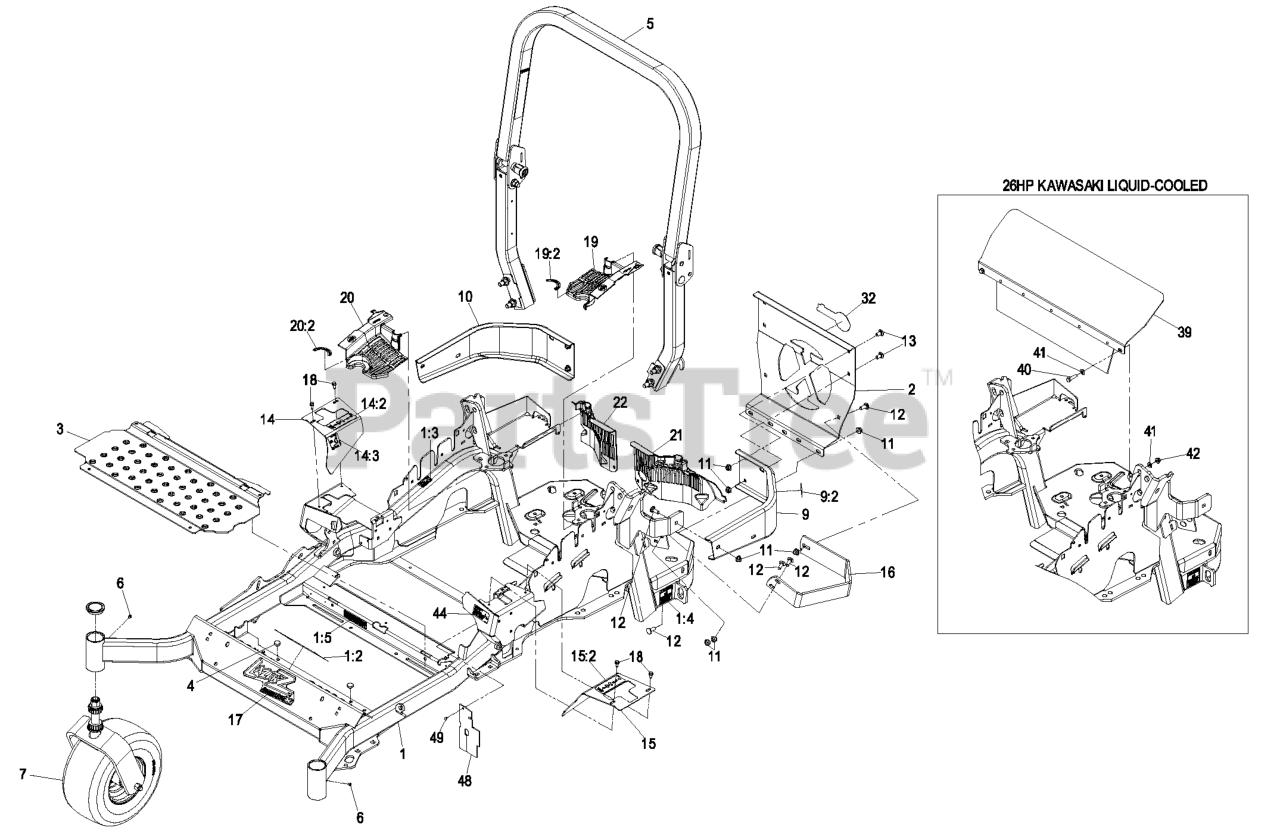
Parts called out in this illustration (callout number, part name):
1	MAIN FRAME ASM
1:2	DECAL-WARNING
1:3	DECAL-CAUTION
1:4	DECAL-BELT DRIVE
1:5	DECAL-ARRESTER, SPARK
2	PLATE,REAR GUARD
5	ASM,ROPS SERVICE EXMARK
9	LH BUMPER ASM
9:2	DECAL-CAUTION
10	BUMPER-RH
11	NUT-HF, NI
12	SCREW-CARR
13	SCREW-CARR
14:2	DECAL-MOTION CONTROL
15	LH MOTION CONTROL COVER ASM
15:2	DECAL-MOTION CONTROL
17	DECAL,LAZER ASX LOGO
18	SCREW-HWH
19	LH HYDRO GUARD ASM
19:2	DECAL-HYDRO OIL
20	RH HYDRO GUARD ASM
20:2	DECAL-HYDRO OIL
21	GUARD-HYDRO, REAR (LH)
22	GUARD-HYDRO, REAR (RH)
39	ASM,AIR DEFLECTOR
40	SCREW-HH
41	WASHER-SPRING
42	NUT-HF, NI
44	DECAL-FUEL FILL
48	DEFLECTOR-AIR FLOW
49	RIVET-POP
